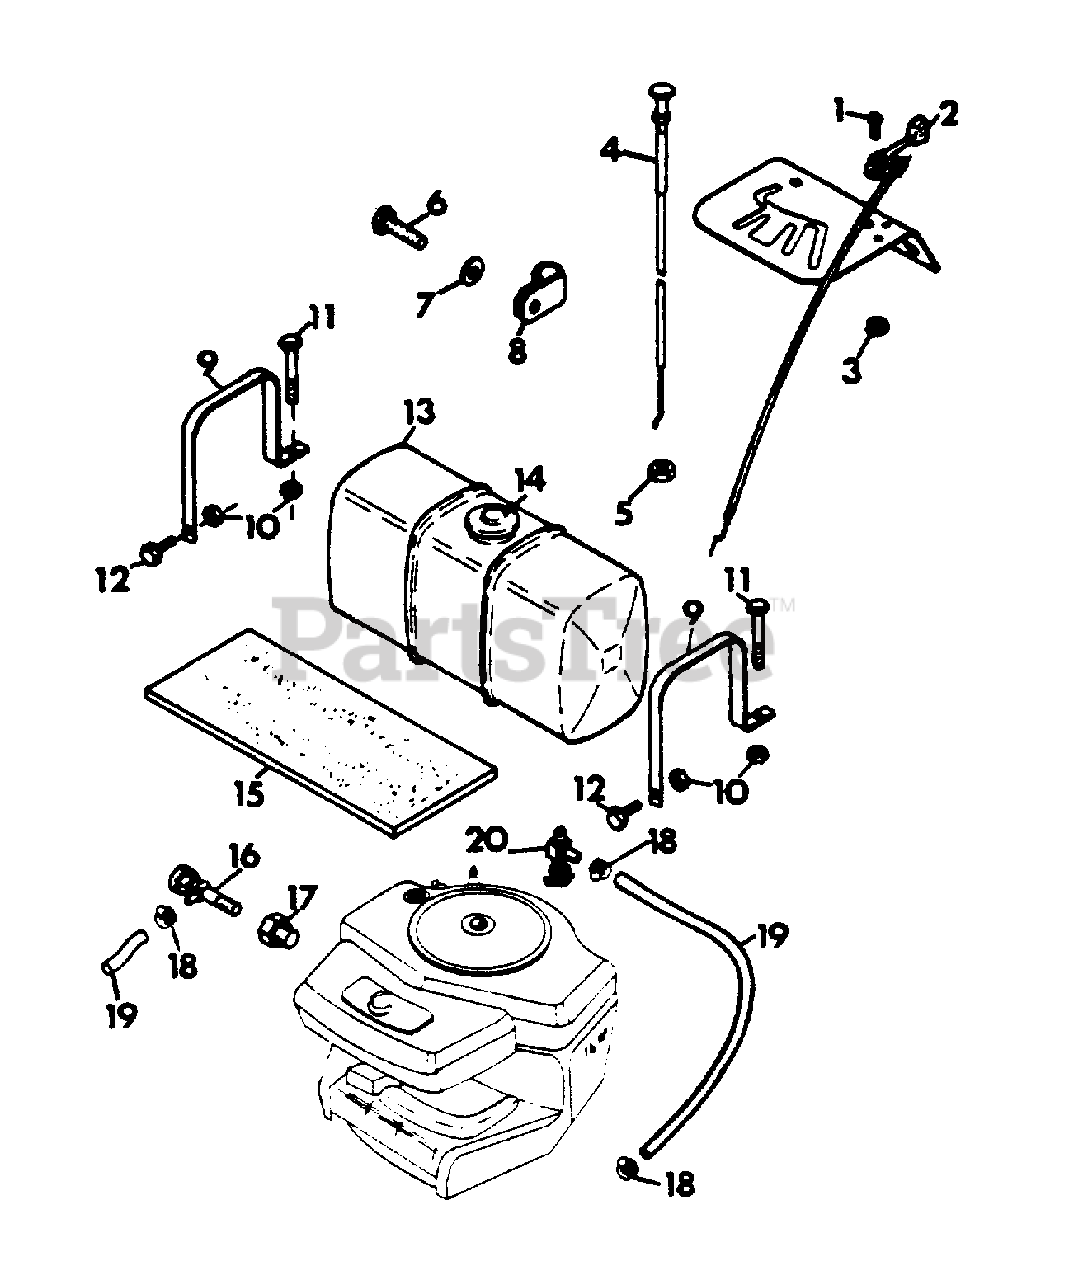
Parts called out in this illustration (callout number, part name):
1	SCREW, MACH. 10-24X.50 PHD
2	LEVER, CONTROL
3	NUT, LOCK 10-24
4	CONTROL, CHOKE
5	NUT, JAM 3/8-24 HEX HEAD
6	BOLT, HEX 1/4-20X1.00
7	WASHER, FLAT .281X.625X.065
8	CLAMP
9	STRAP, FUEL TANK
10	NUT, LOCK 1/4-20
11	BOLT, HEX 1/4-20X1.75
12	BOLT, HEX 1/4-20X.625
13	TANK, FUEL (12 QTS.)
14	CAP, FUEL TANK
15	PAD, FUEL TANK
16	COCK, OIL DRAIN
17	ADAPTOR, OIL DRAIN
18	CLAMP, HOSE
19	LINE, FUEL
20	VALVE AND STRAINER
